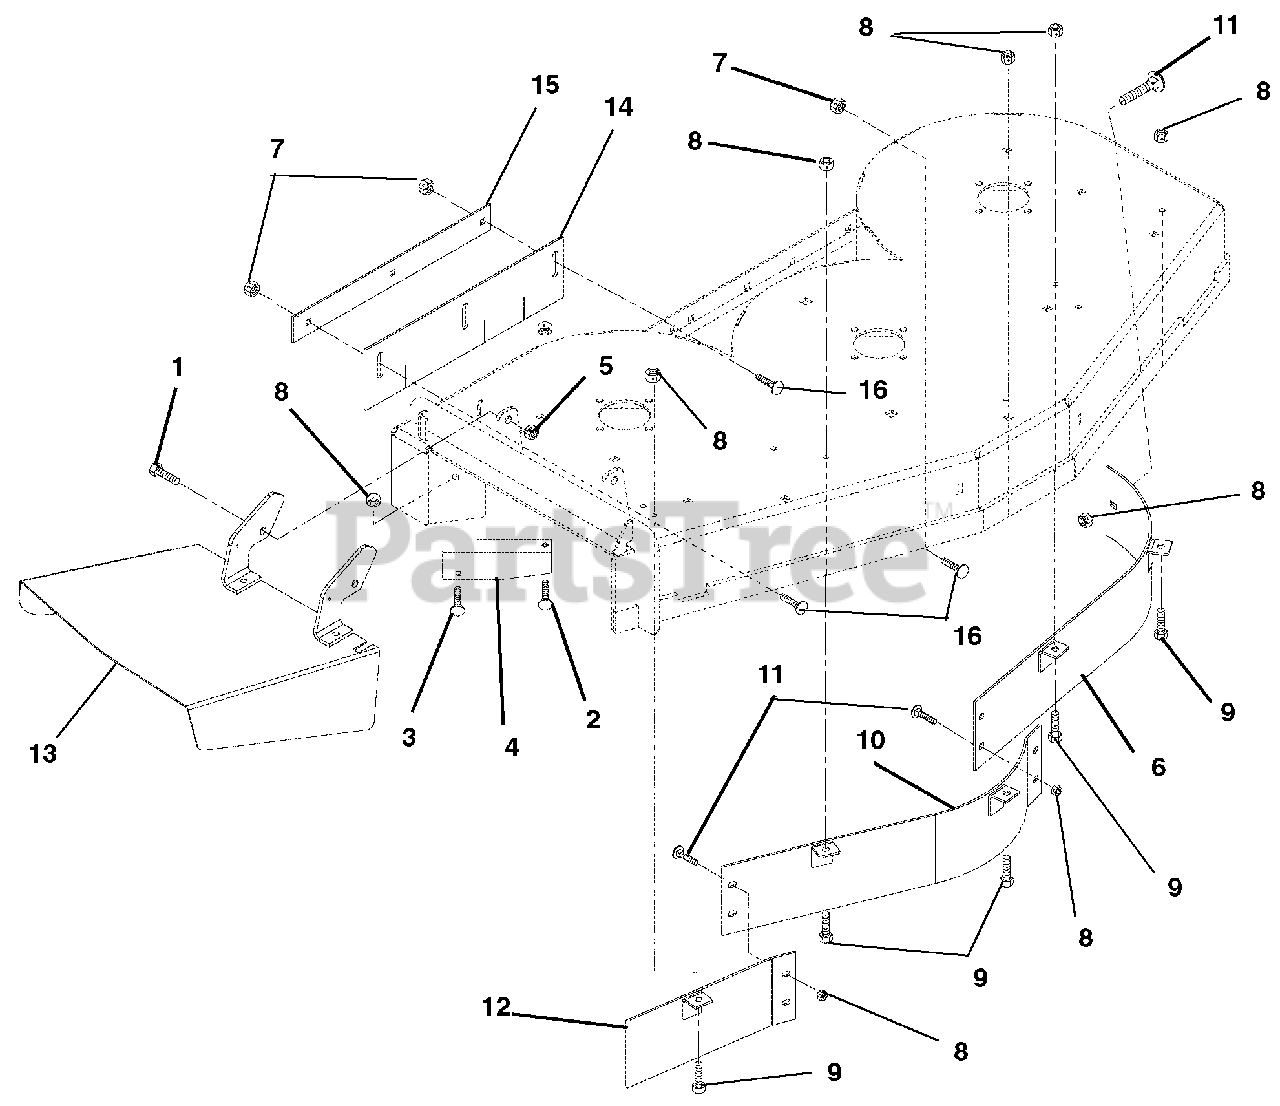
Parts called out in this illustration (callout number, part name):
1	@BLT-HEX .50-13X1.25 GR5 YWZC
2	@BLT-RDHDSQNK .38-16X.75 G5YZ
3	@BLT-RDHDSQNK .31-18X.75 G5YZ
4	DEFLECTOR - 44"/48"
5	@NUT-LK-NYL .50-13 YWZC
6	BAFFLE - LEFT FRONT - 48"
7	@NUT-LK-TOP-FLG .38-16 YWZC
8	@NUT-LK-TOP-FLG .31-18 YWZC
9	@BLT-HEX .31-18X.75 GR5 YWZC
10	BAFFLE - CENTER FRONT - 48"
11	@BLT-RDHDSQNK .31-18X.75 G5YZ
12	BAFFLE - RIGHT FRONT - 48"
13	WMT - DISCHARGE CHUTE - PRO
14	SKIRT- RUBBER
15	STRIP - STRIPER MOUNT
16	@BLT-RDHDSQNK .38-16X1.00 G5YZ
